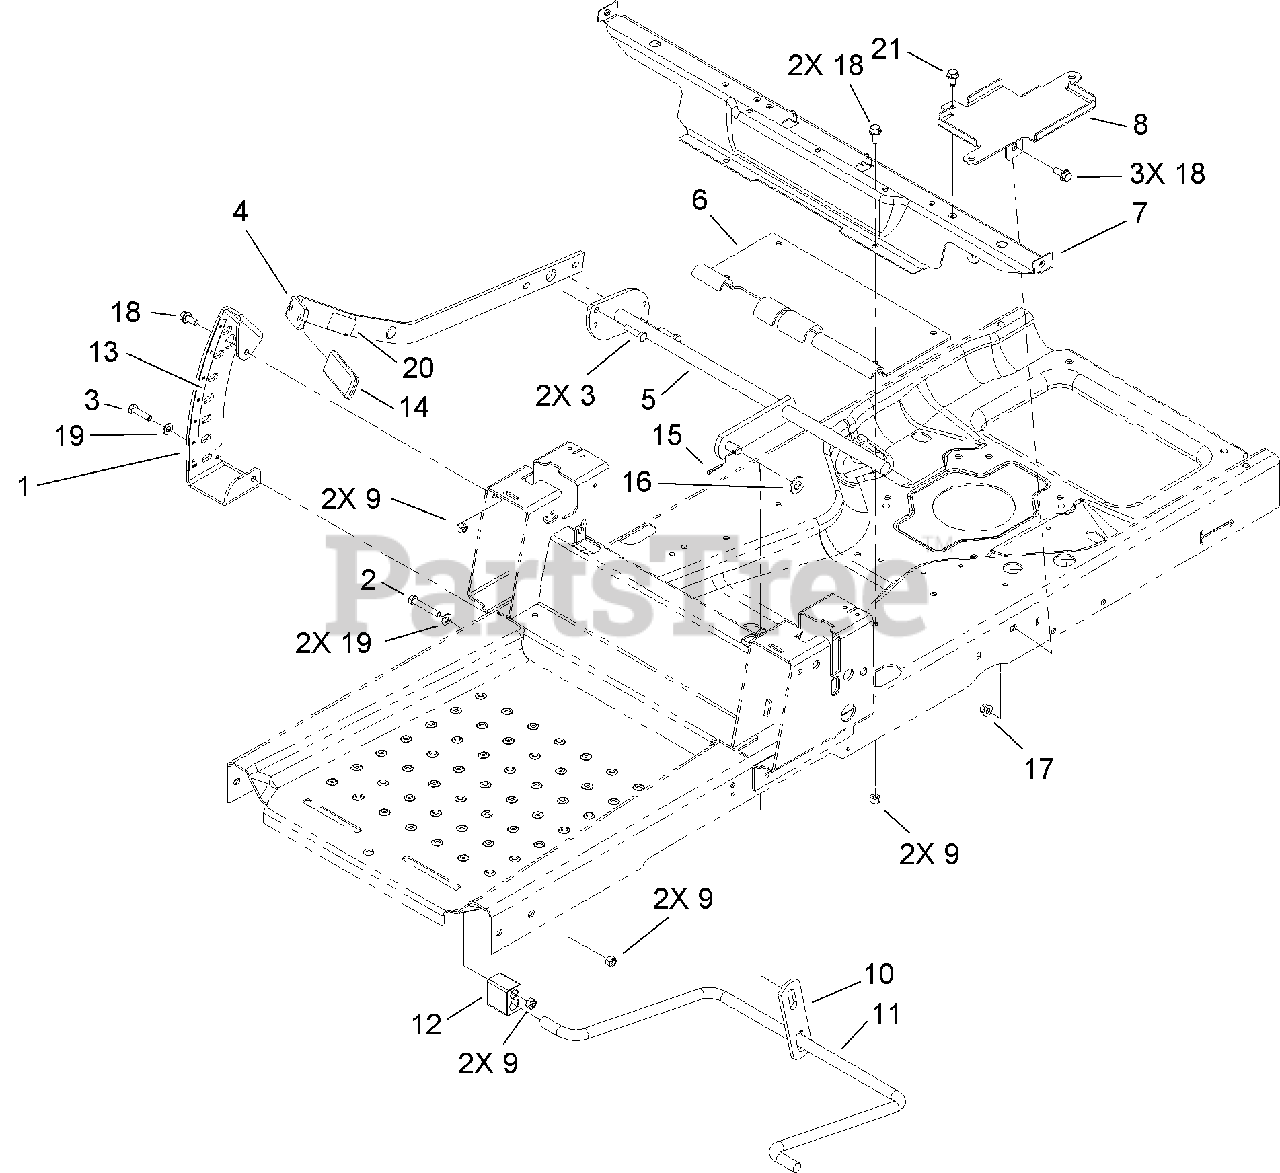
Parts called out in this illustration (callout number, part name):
2	SCREW-HH
3	SCREW-HH
4	LIFT ARM ASM
5	LIFT LEVER ASM
7	BRACKET-SEAT/PODS
8	TRAY-BATTERY
9	NUT-LOCK, NI
10	LINK-LIFT
11	ARM-LIFT, REAR
12	BLOCK-PIVOT
13	DECAL-HOC
14	GRIP-LEVER, LIFT
15	PIN-COTTER
16	WASHER-FLAT
17	NUT-LOCK, NI
18	SCREW-HHF
19	WASHER-FLAT
21	SCREW-HWH
